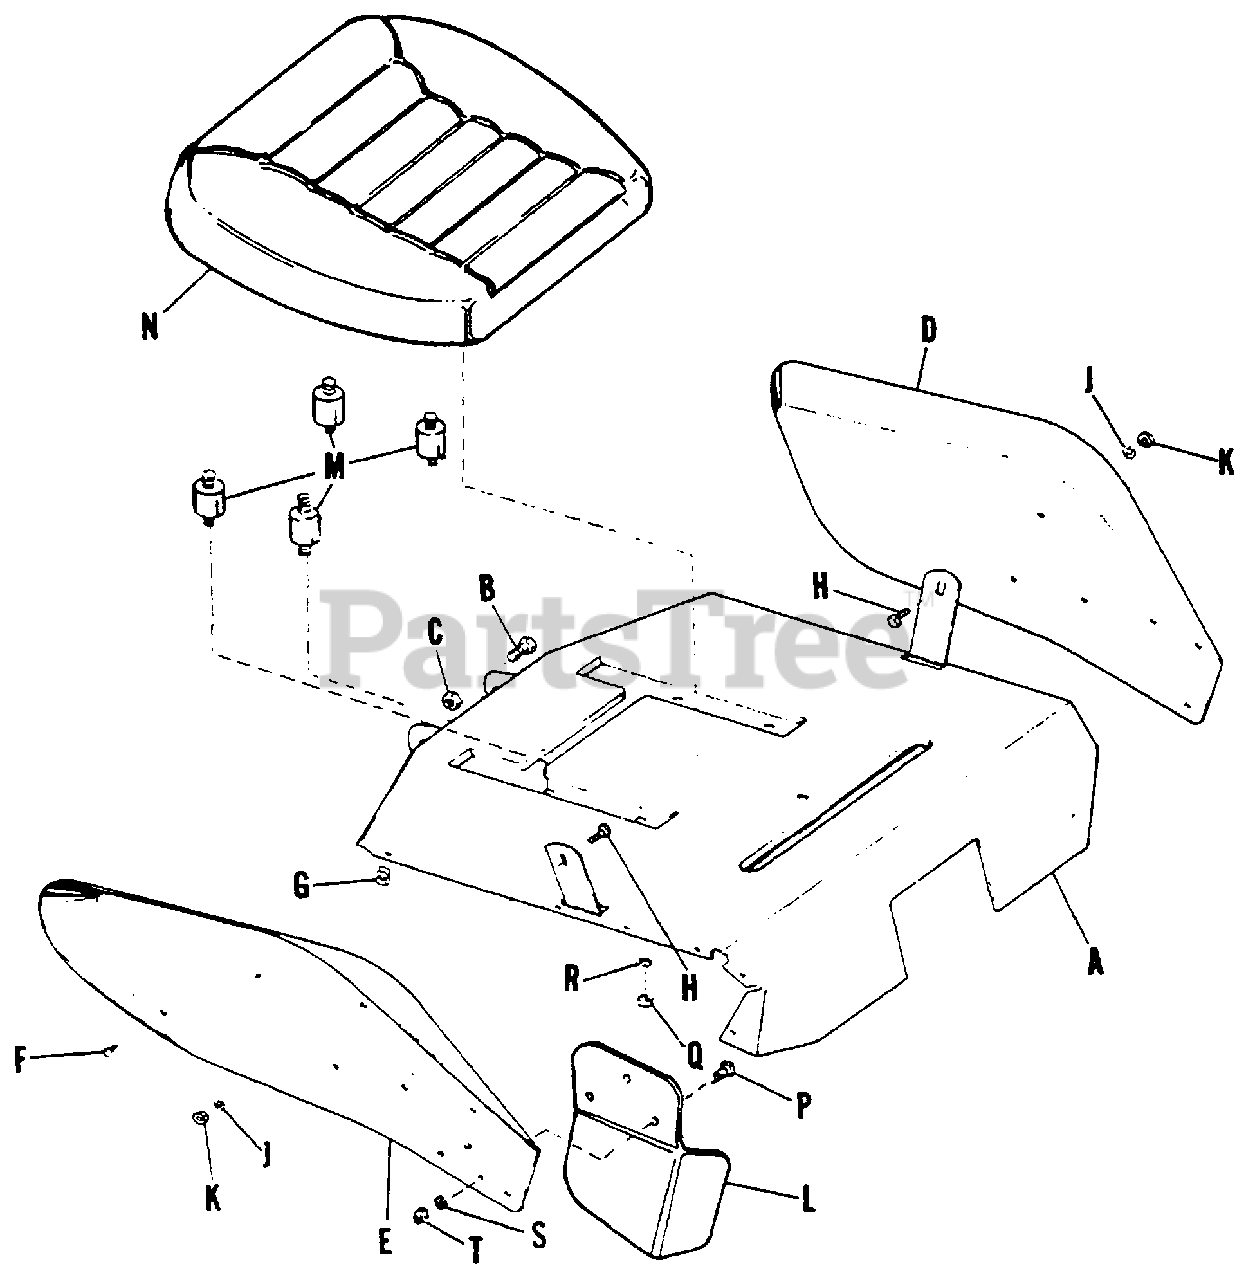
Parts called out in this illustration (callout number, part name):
A	Cover and Seat Pivot Assembly
B	Screw, Cap, Hex, 3/8Ó - 16 NC x 1Ó lg.
C	Nut, Lock, Full, Hex, 3/8Ó - 16 NC
D	Fender, L.H.
E	Fender, R.H.
F	Screw, self-tapping, #10 x 1/2Ó lg.
G	Nut, Speed, Tinnerman
H	Screw, Cap, Hex, 1/4Ó - 20 NC x 1/2Ó lg.
J	Washer, Lock, 1/4Ó
K	Nut, Hex, Full, 1/4Ó - 20 NC
L	Guard, Starter Cup
M	Connector, Cushion
N	Seat Assembly
P	Capscrew, Hex Hd., 1/4Ó - 20 - 1/2Ó lg.
Q	Hex Nut, Full, 5/16Ó - 18
R	Lock Washer, 5/16Ó
S	Lock Washer, 1/4Ó
T	Hex Nut, Full, 1/4Ó - 20
